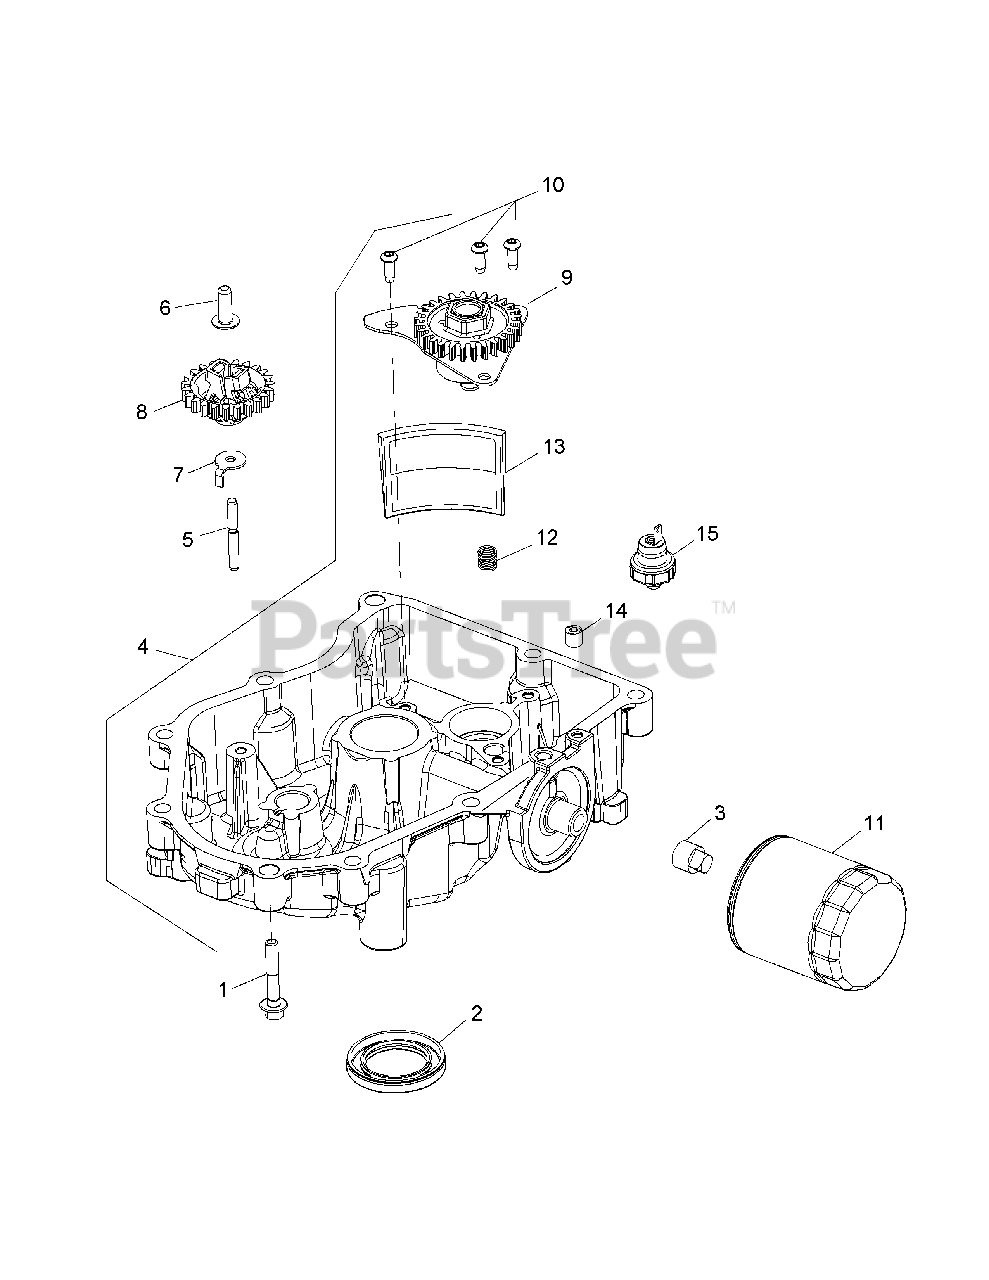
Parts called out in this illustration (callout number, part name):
1	Flange Screw, M8 x 1.25 x 45
2	Oil Seal, 2.38 x 1.45
3	Square Head Pipe Plug, 3/8
4	Oil Pan Assembly
5	Governor Gear Shaft
6	Governor Regulating Pin
8	Governor Gear Kit
9	Oil Pump Assembly
10	Button Head Screw
12	Compression Spring
14	Pipe Plug, 1/8
